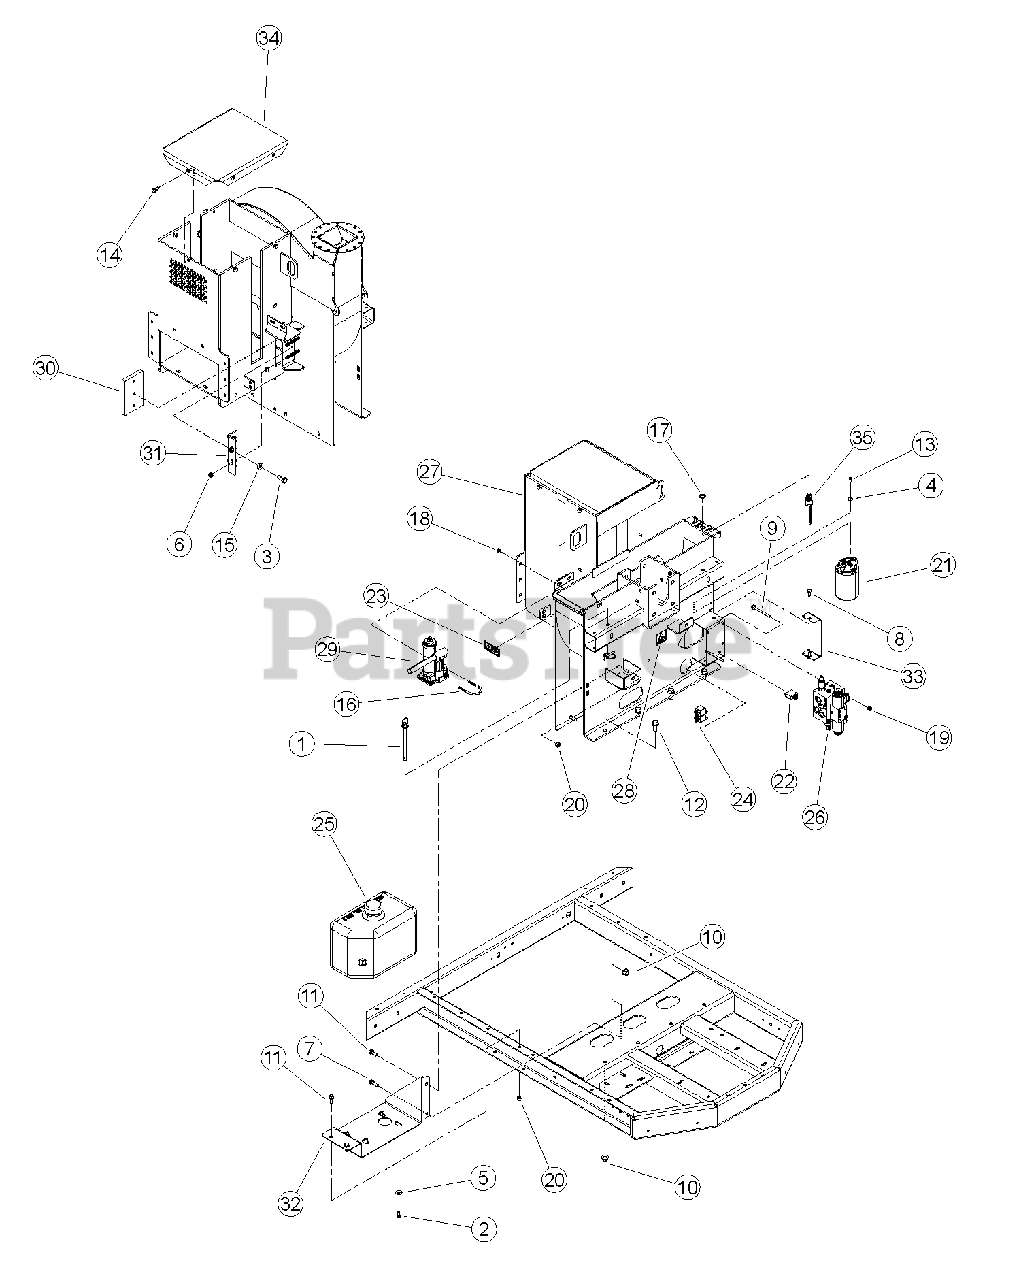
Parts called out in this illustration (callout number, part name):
1	PIN, HITCH 1/2 X 6-1/2 W/ LYNCH
2	BOLT, 3/8 X 3/4 GR5 HEX CAPSCREW ZP
3	BOLT, 1/2 X 1-1/4" GR5 HHCS NC ZP
4	WASHER, 1/4" FLAT ZP
5	WASHER, 3/8" FLAT ZP
6	NUT, 3/8" SERRATED FLANGE NC ZP
7	BOLT, 3/8 X 1-1/4 FLANGE NC
8	BOLT, 5/16 X 3/4 FLANGE NC
9	BOLT, 5/16 X 3-1/2 SERRATED FLANGE NC
10	NUT, 1/2-13 NYLOCK FLANGE
11	BOLT, 3/8 X 1 FLANGE NC
12	BOLT, 1/2 -13 X 1-1/4 FLANGE NC
13	BOLT, 1/4 X 5/8" HHCS GR5 ZP
14	BOLT, 3/8 X 3/4" SERRATED FLANGE
15	WASHER, 1/2 HI-STRENGTH SAE ZP
16	U-BOLT, 1/4 X 1-1/2 PIPE
17	NUT, 5/8-32 JAM
18	NUT, 1/4-20 NYLOCK-FLANGE
19	NUT, 5/16-18 NYLOCK-FLANGE
20	NUT, 3/8-16 NYLOCK FLANGE
21	ASSEMBLY, HYDRAULIC FILTER
22	CIRCUIT BREAKER, 10 AMP RESETTABLE
23	DECAL, CRUSHING ISO
24	RELAY, 12V SPDT W/ FLANGE
25	TANK, HYDRAULIC
26	ASSEMBLY, HYDRAULIC FEED FLOW VALVE W/ PS
27	ASSEMBLY, 6" CHIPPER HOUSING WITH DECALS
28	DECAL, SHIELD DANGER ISO
29	JACK, HYDRAULIC 2 TON
30	ANVIL, 6" CHIPPER
31	WELDMENT, BLOCK ADJUSTOR
32	BRACKET, HYDRAULIC TANK
33	COVER, CHIPPER SHAFT
34	WELDMENT, TOP ROLLER COVER
35	ASSEMBLY, SEALED SWITCH
